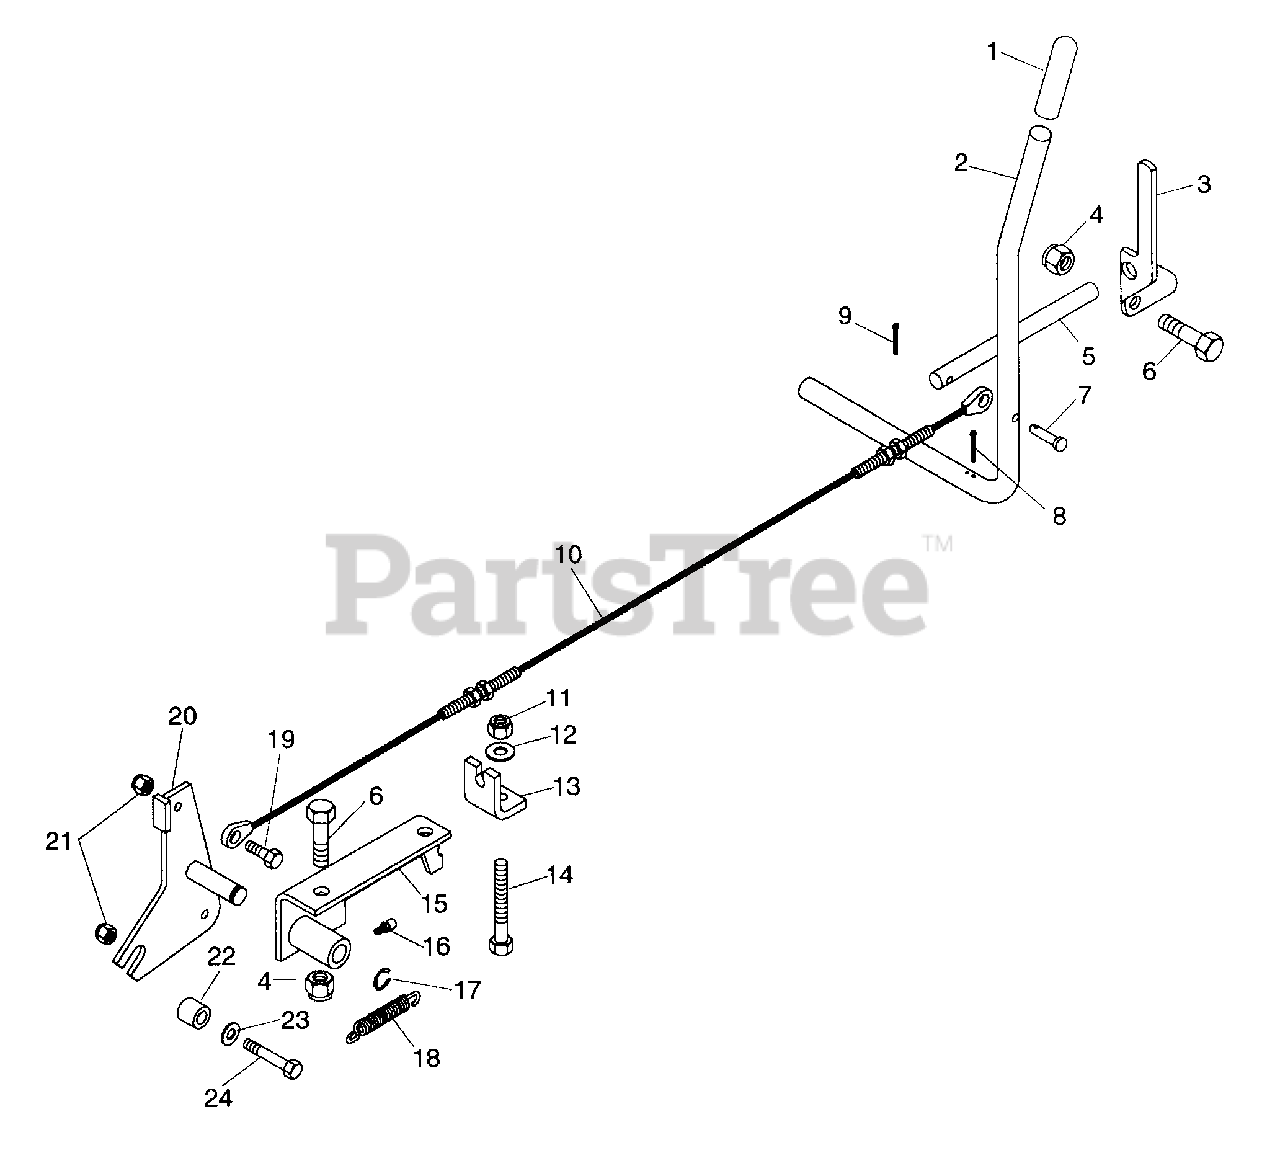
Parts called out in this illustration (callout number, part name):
1	Grip, Handle
2	Lever, Brake
3	Arm, Parking Brake Lock
4	Nut-Locking-Nylon .375-16
5	Rod, Brake Lock
6	Bolt-Hex .38-16 x 1.00 Grade 5
7	Pin-Clevis .25 x 1.75
8	Pin-Cotter .094 x 1.25
9	Pin-Cotter .09 x .75
10	Cable, Brake
11	Nut-Locking-Nylon .312-18
12	Washer-Flat-Steel .344 x .688 x .065
13	Bracket, Cable
14	Bolt-Hex .31-18 x 1.00 Grade 5
15	Weldment, Brake Pivot
16	Fitting-Lube .25-28 x .256
17	Ring-Retaining-External .392 x .042
18	Spring-Tension .093 x .75 x 4.0
19	Bolt-Hex .25-20 x .875
20	Weldment, Brake Arm
21	Nut-Locking-Nylon .250-20
22	Bushing, Sleeve .260 x .500 x .750
23	Washer-Flat-Steel .281 x .620 x .065
24	Bolt-Hex .250-20 x 1.75 Grade 2
